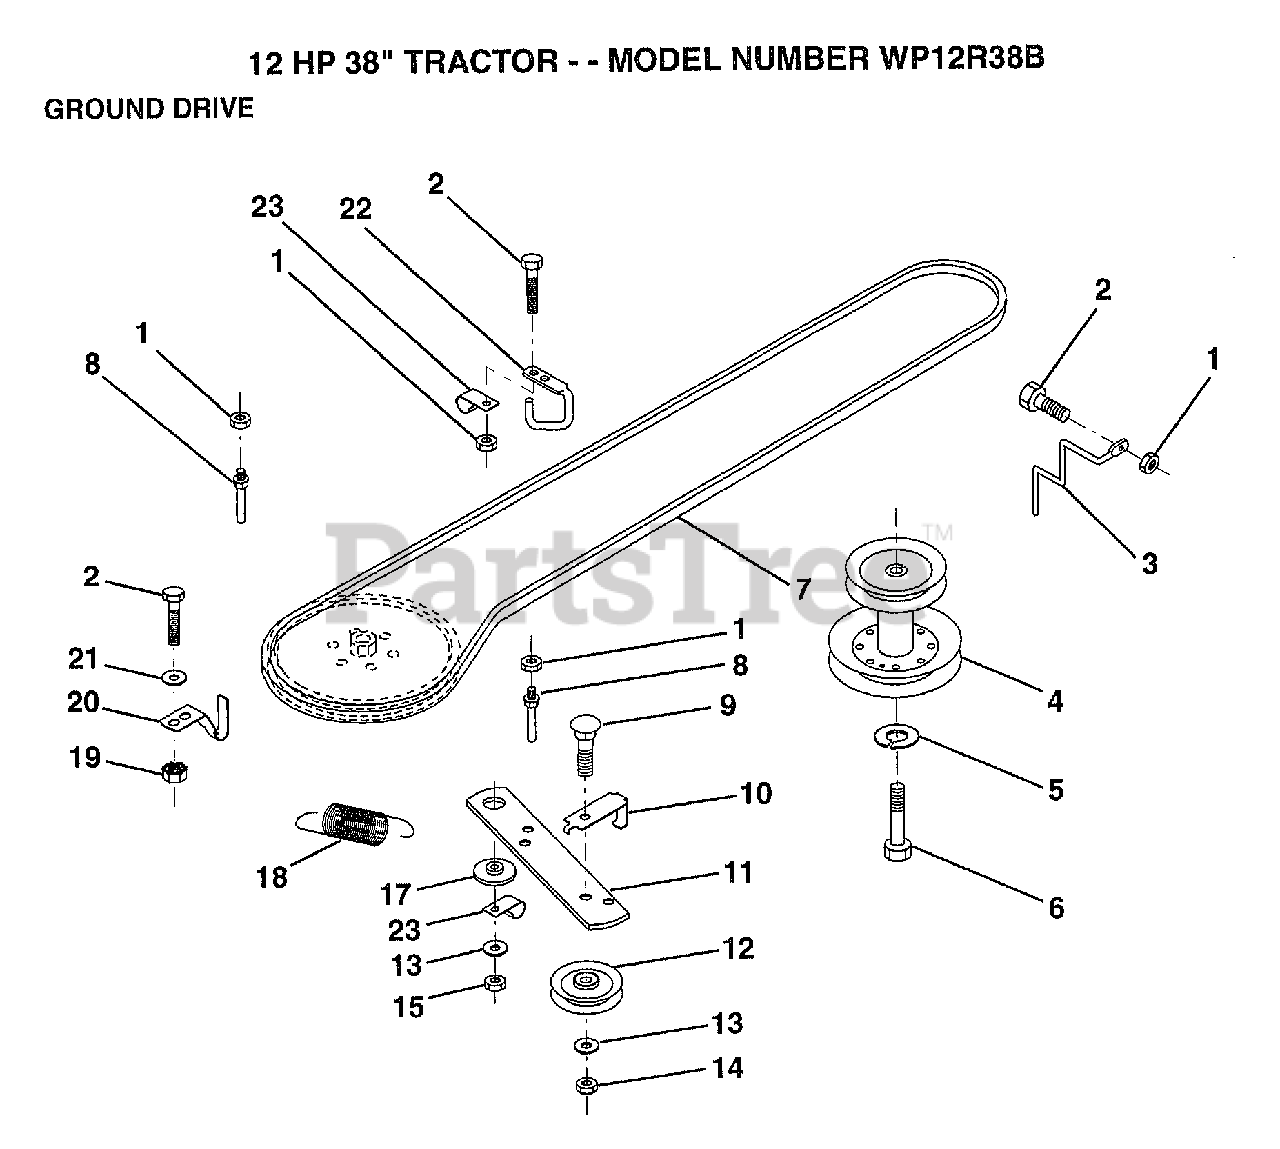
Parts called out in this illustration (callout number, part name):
2	BOLT
3	KEEPER MWR DR BLT
4	PULLEY.ENGINE.LR
5	LOCKWASHER
6	HEX BOLT
7	BELT
8	"KEEPER,DRIVE BELT"
9	BOLT
10	"KEEP,IDLER DR BEL"
12	PULLEY.IDLER.FLAT
13	WASHER
14	LOCKNUT
17	SPACER RETAINER
20	KEEPER.BELT.T/A
21	WASHER
22	"KEEPER,FRA DR BEL"
23	CLIP INSULATOR
